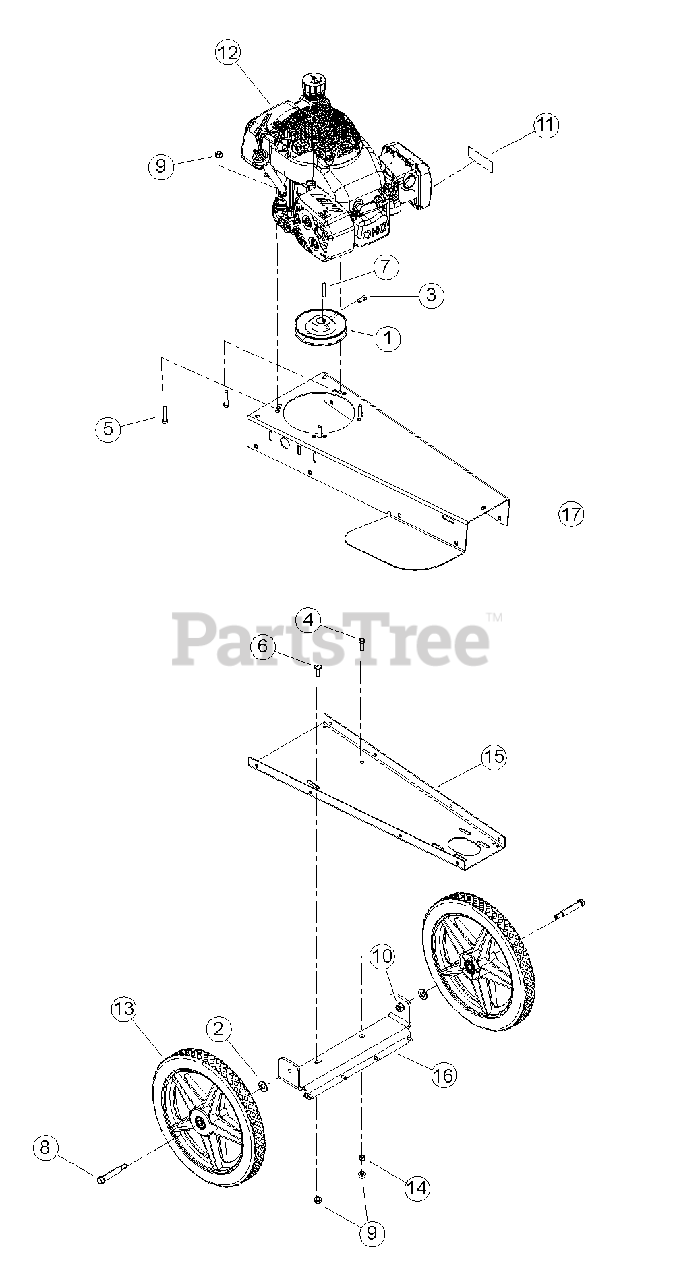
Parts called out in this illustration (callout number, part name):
1	PULLEY, 5.0 X 7/8 AB
2	WASHER, 1/2 SAE FLAT
3	SCREW, 5/16-18 X 5/8 SQ HD SET
4	BOLT, 5/16 X 1 HHCS GR5 NC ZP
5	BOLT, 5/16 X 1-1/2 HEX HD GR5 ZP
6	BOLT, 5/16 X 1 CRG GR5 ZP
7	KEY, 3/16 SQUARE X 1-1/2 LONG PLAIN
8	BOLT, 3/8-16 X 3-1/4 ZP FLANGE SHOULDER
9	NUT, 5/16-18 NYLOCK FLANGE
10	NUT, 3/8-16 NYLOCK FLANGE
11	DECAL, SERIAL NUMBER
13	WHEEL, 14 X 1/75 TRIMMER
14	SPACER, .334 X .50 X .29
15	BOTTOM, TRIMMER FRAME
16	PLATE, WT190 AXLE
17	BODY, TRIMMER
